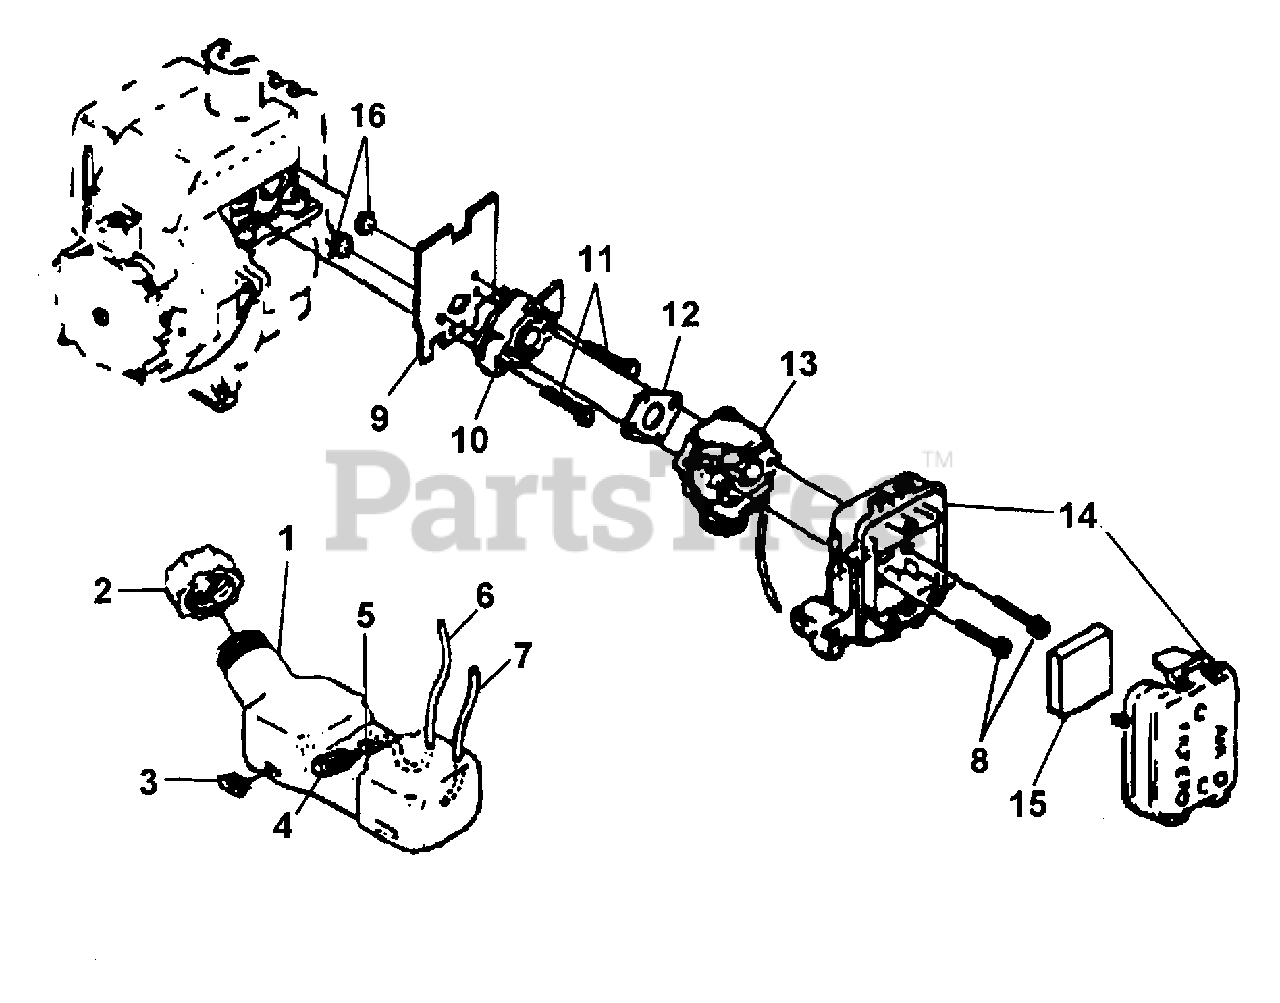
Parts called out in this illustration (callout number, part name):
1	FUEL TANK
2	TUBING, FUEL 4 1/4"
3	TUBING, FUEL 7 1/2"
4	CLAMP, FUEL LINE
5	FILTER, FUEL
6	BUMPER, RUBBER
7	FUEL CAP
8	SCREW, SEMS HEX HEAD 10-24 X 2 1/4"
9	GASKET, HEAT DAM
10	HEAT DAM
11	SCREW, TORX, SEMS 10-24 X 1/8"
12	GASKET CARBURETOR
13	CARBURETOR, ZAMA
14	AIR FILTER ASSY.
15	AIR FILTER
16	NUT, HEX 10-24
